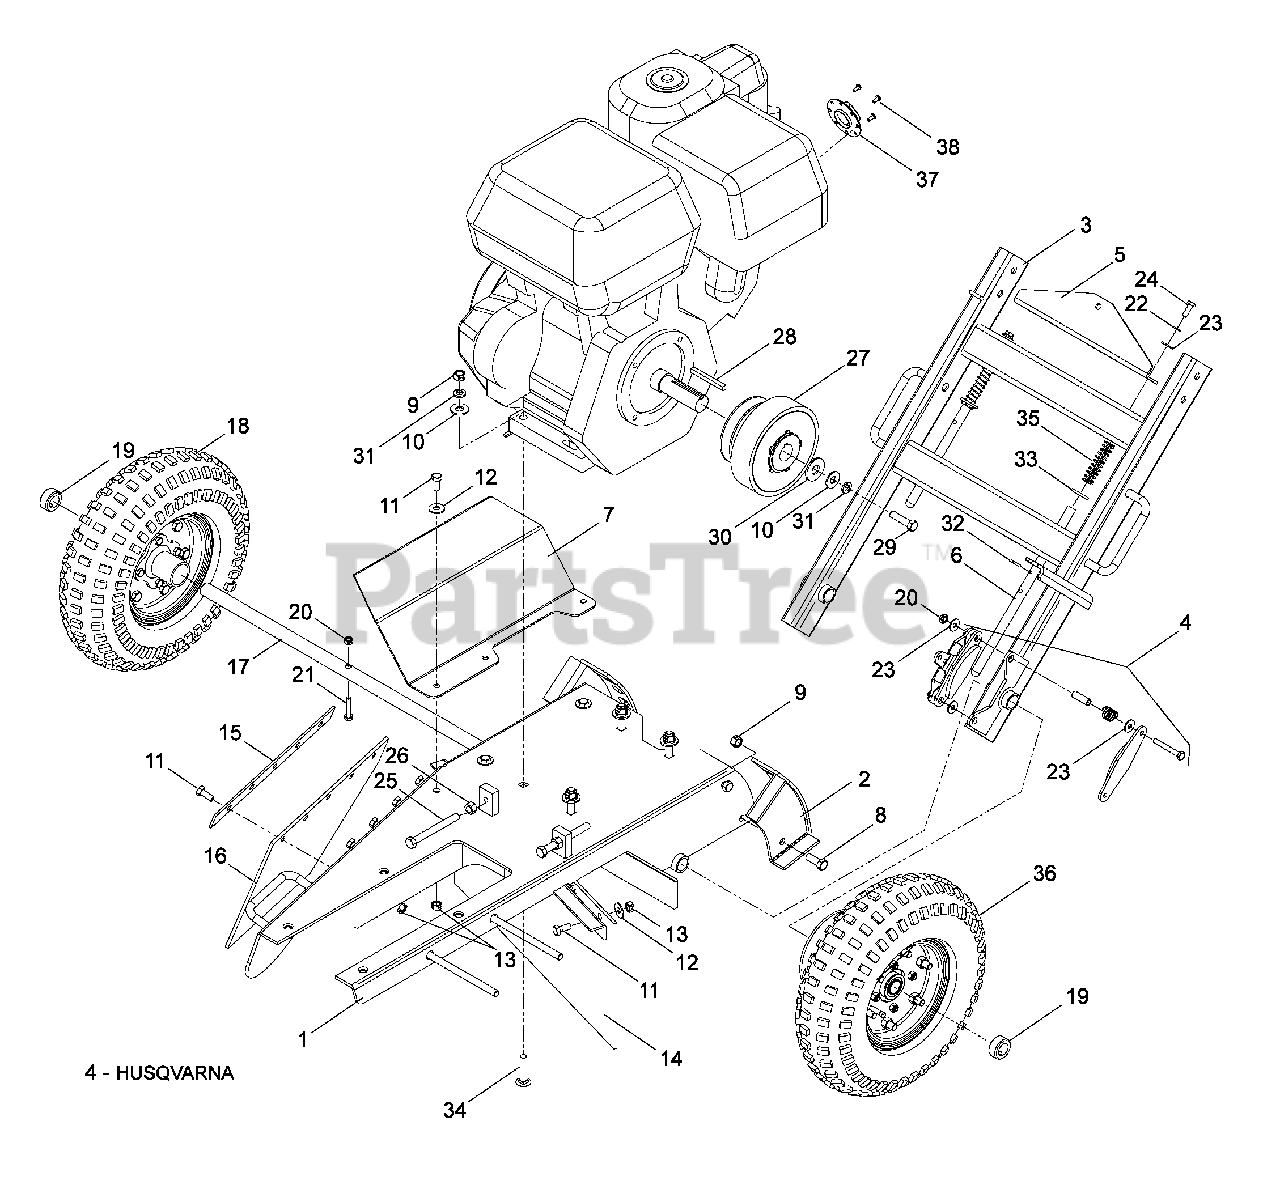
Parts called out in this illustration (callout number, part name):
3	HANDLE, LOWER
4	BRAKE, CALIPER
5	BRACKET, HANDLE
6	PIN, HANDLE ADJUSTMENT
8	HCS 3/8-16 x 1
9	NUT 3/8-16 CNTRLK
10	WASHER 3/8 FLAT STD
11	HCS 5/16-18 x ¾
12	WASHER 5/16
13	NUT 5/16-18 CNTRLK
14	DEFLECTOR, REAR
15	STRAP, DEFLECTOR
16	DEFLECTOR, SIDE
19	SET COLLAR, ¾"
20	NUT ¼-20 CNTRLK
21	HCS ¼-20 x 1¼
22	LOCKWASHER ¼
24	HCS ¼-20 x ¾
25	HCS 3/8-16 x 3½ TPBLT
26	NUT 3/8-16
27	CLUTCH -NORAM 3 SHOE
28	KEY ¼ SQ x 2½
29	HCS 3/8-24 x 1½
30	WASHER ½ FLAT
31	WASHER 3/8 SPLIT LK
32	PIN, COTTER 1/8 x ¾
33	WASHER ½, SAE
34	RHSNB 3/8-16 x 1¾
35	SPRING, COMPRESSION
36	WHEEL w/ DISC
37	DEFLECTOR, EXHAUST
38	SCREW #8-32 x 3/8
